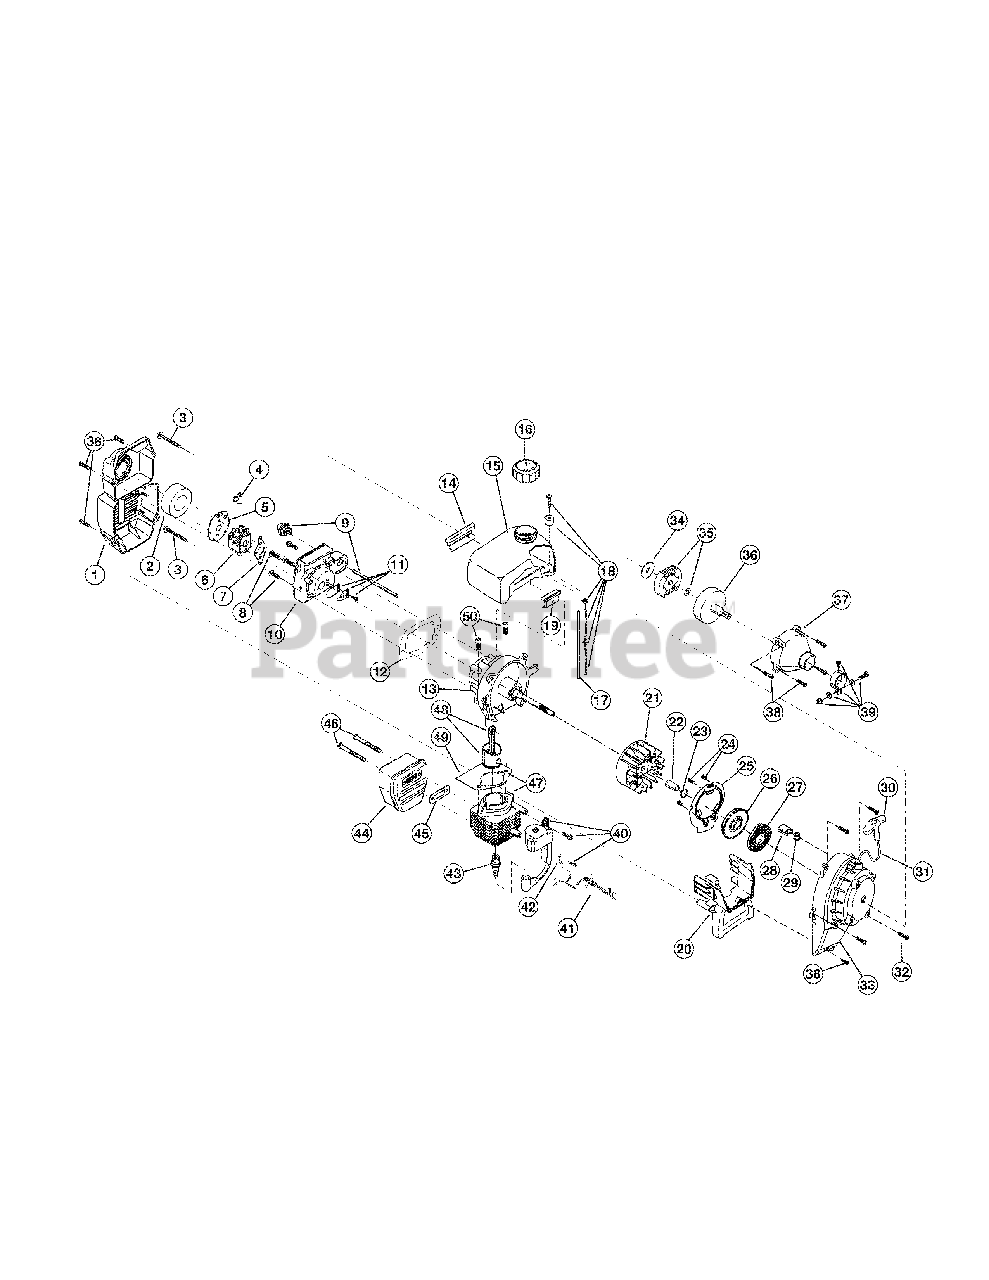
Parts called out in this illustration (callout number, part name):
1	Air Cleaner Assembly (includes 2 & 38)
2	Air Cleaner Filter
3	Carburetor Mounting Screw Assembly
4	Choke Extension
5	Choke Plate
6	Carburetor Assembly (includes 7 & 18)
7	Carburetor Gasket
8	Carb Mount Screw
9	Primer and Hose Assembly
10	Carb Mount Assembly (includes 8, 11 & 12)
11	Reed Assembly
12	Carburetor Mount Gasket
13	Crank Case Service Assembly (includes 8)
14	Rear Mounting Pad
15	Fuel Tank Assembly (includes 16-18)
16	Fuel Cap Assembly
17	Fuel Return Line
18	Fuel Line Assembly
19	Front Mounting Pad
20	Shroud Extension and Stand (includes 38)
21	Flywheel Assembly
23	Pulley Retainer
24	Plate Screw
25	Pressure Plate (includes 24)
26	Recoil Pulley Assembly (includes 23 & 31)
27	Recoil Spring
28	Eyelet Retainer
29	Rope Guide
30	Pull Handle
32	Housing Screw
33	Starter Housing Assembly (includes items 23-32 & 38)
34	Clutch Washer
35	Clutch Rotor Assembly
36	Clutch Drum Assembly
37	Clutch Cover Assembly (includes 38)
38	Clutch Cover Screw
39	Upper Clamp Assembly
40	Module Assembly (includes 42)
41	Wire Lead
42	Ground Tab
43	Spark Plug
44	Muffler Assembly (includes item 45 & 46)
45	Exhaust Gasket
46	Muffler Mounting Bolt Assembly
47	Cylinder Assembly (includes items 49 & 50)
48	Piston & Rod Assembly
49	Cylinder Gasket
50	Cylinder Bolt
